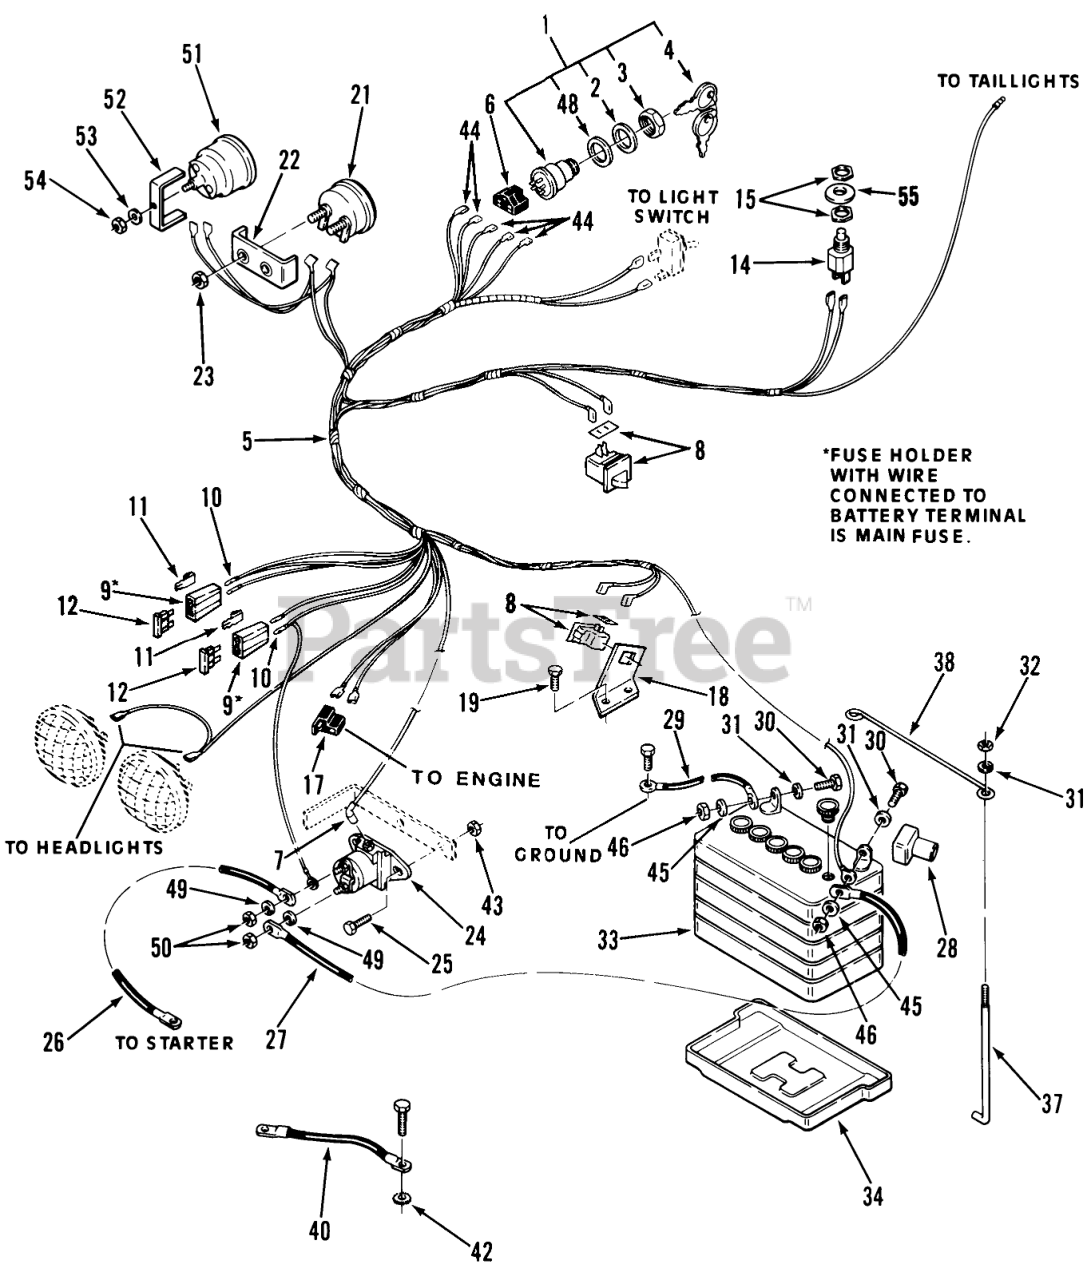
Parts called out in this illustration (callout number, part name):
1	SWITCH-IGNITION
12	FUSE-BLADE, 5 AMP
12	FUSE-BLADE, 15 AMP
12	FUSE-BLADE, 25 AMP
14	SWITCH
15	NUT-HEX
17	CONNECTOR BODY
18	BRACKET-SWITCH (NS)
19	Bolt
22	CLAMP MOUNTING
23	HEX NUT 10-32 E.S. + + USE 3296-21 + +
26	ASSY STARTER WIRE
27	CABLE-BLACK
33	OBTAIN LOCALLY
34	TRAY BATTERY
38	ROD-HOLD DOWN
40	WIRE-GROUND
55	WASHER-FLAT
